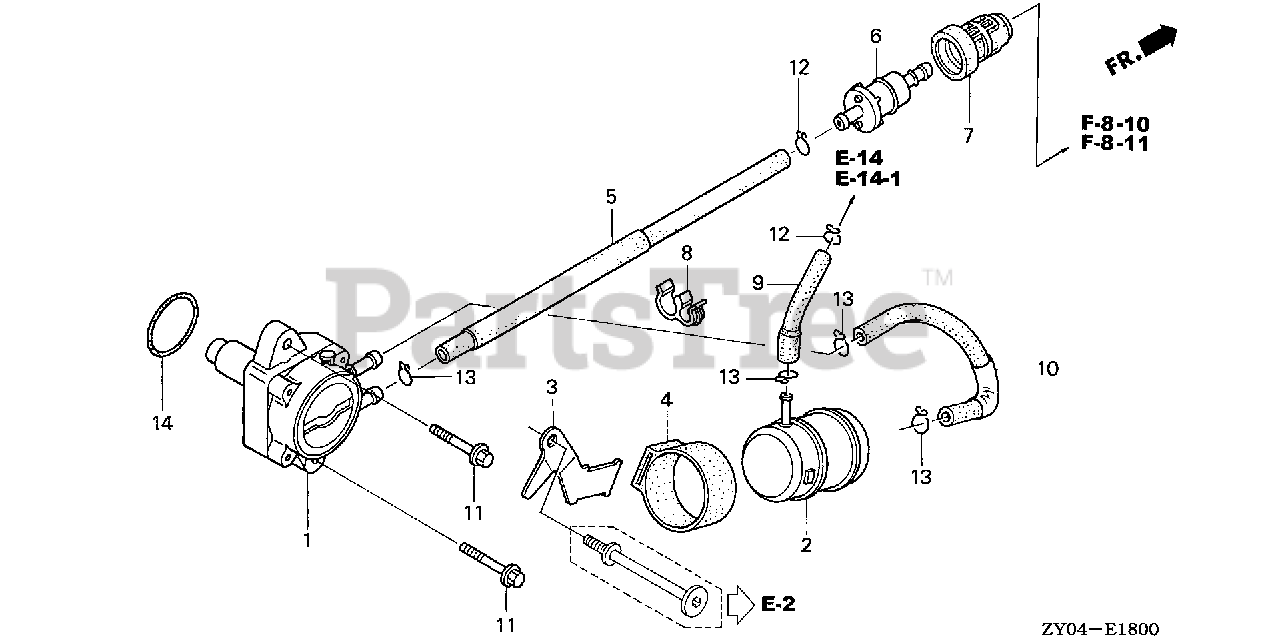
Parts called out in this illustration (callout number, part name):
1	PUMP ASSY., FUEL (MSDS)
2	CHAMBER KIT, FUEL
3	STAY, FUEL CHAMBER
4	SUSPENSION, FUEL CHAMBER
5	TUBE B, FUEL
6	FILTER, FUEL
7	SUSPENSION, STRAINER
8	CLAMP, TUBE (7.5-11.5) (BLACK)
9	TUBE D, FUEL
10	TUBE C, FUEL
11	BOLT, FLANGE (6X22)
12	CLIP, TUBE (B10)
13	CLIP, TUBE (B12)
14	O-RING (31.2X2.4)
